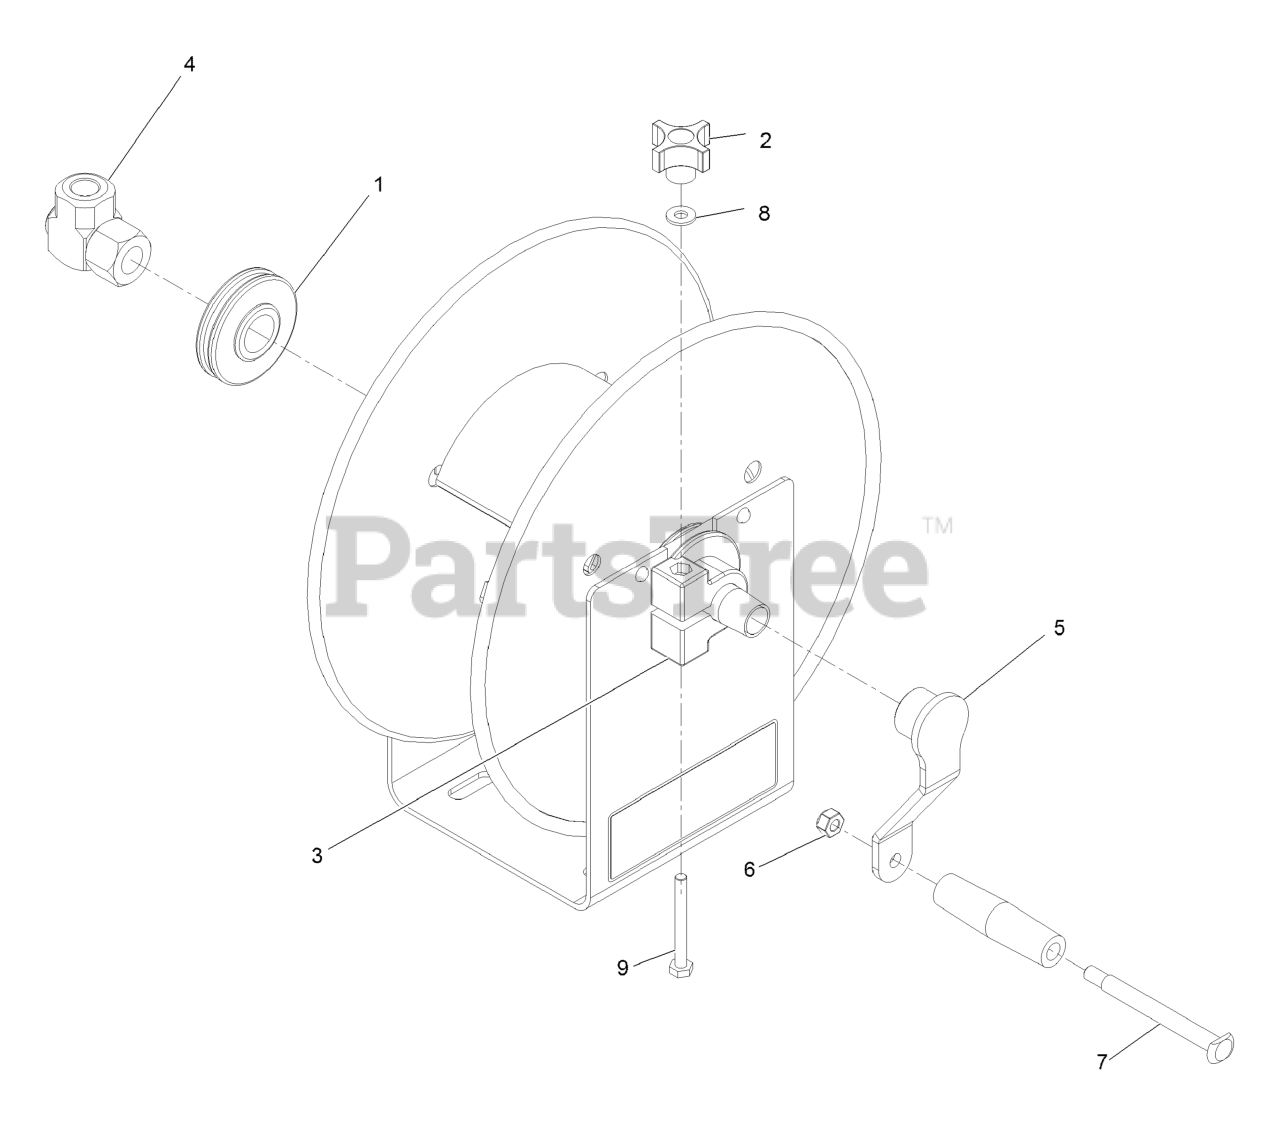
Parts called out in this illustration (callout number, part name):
1	PLASTIC BEARING
2	HOSE REEL BRAKE KNOB
3	BRAKE/BEARING 6329-1-1
4	SWIVEL 3/8" NPT
5	Crank-Reel
6	NUT-HEX
7	BOLT, HOSE REEL HANDLE
8	Washer-Flat
9	SCREW-HH
